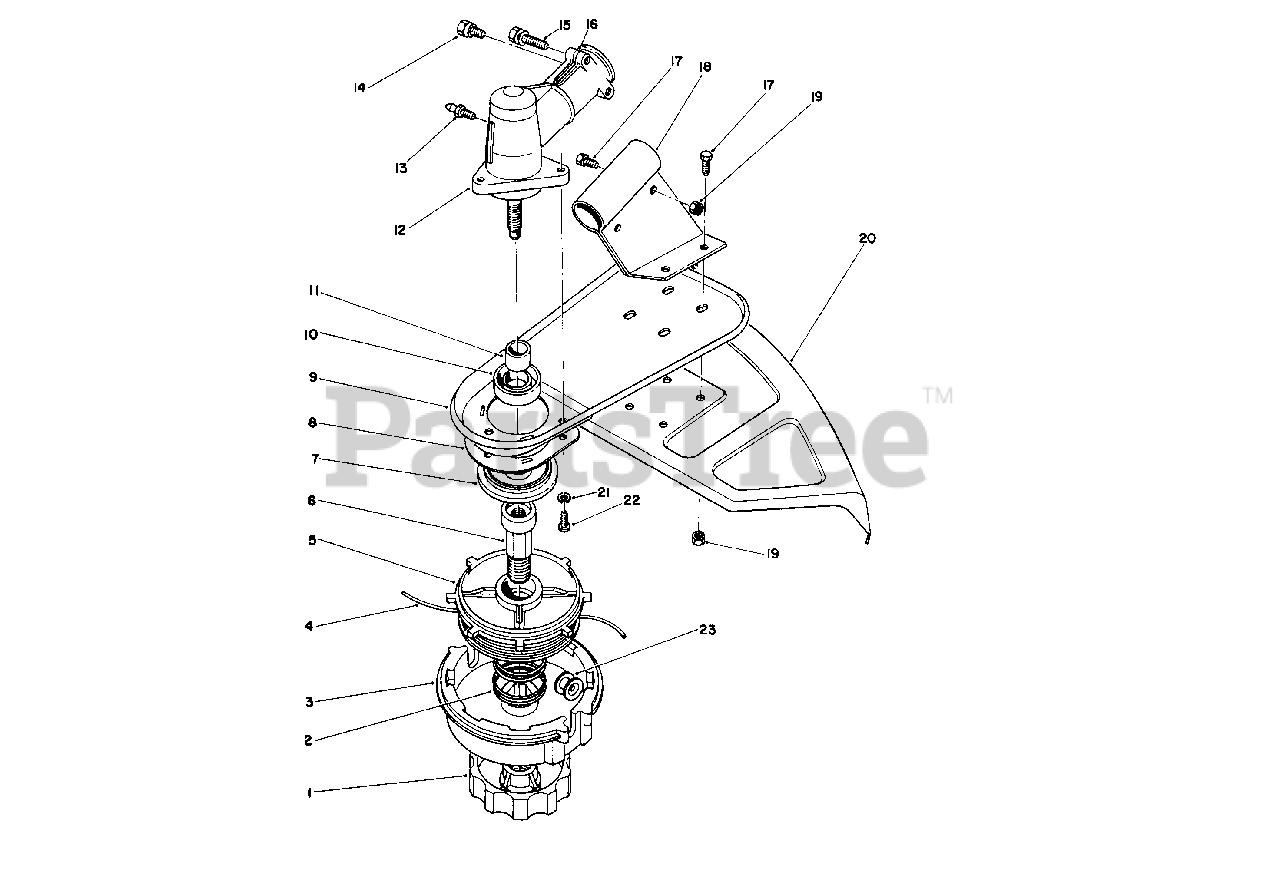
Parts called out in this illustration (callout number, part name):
1	Knob-L.H.
3	Spool-Housing Assembly
5	Spool-Inner 1
7	Cap-Dust
8	Guard-Grass Wrap
9	Support-Shield
10	Seal-Oil
11	Sleeve-Spline
12	Gear Box Assembly (Incl. Ref. #10, 11, & 13-16)
13	Fitting-Grease
14	Screw-Hex. Hd.
15	Screw-Hex. Hd.
16	Washer-Flat
17	Screw-Hex. Hd.
18	Bracket-Shield
19	Nut-Lock
20	Shield-Grass
21	Washer-Lock
22	Screw-Guard
